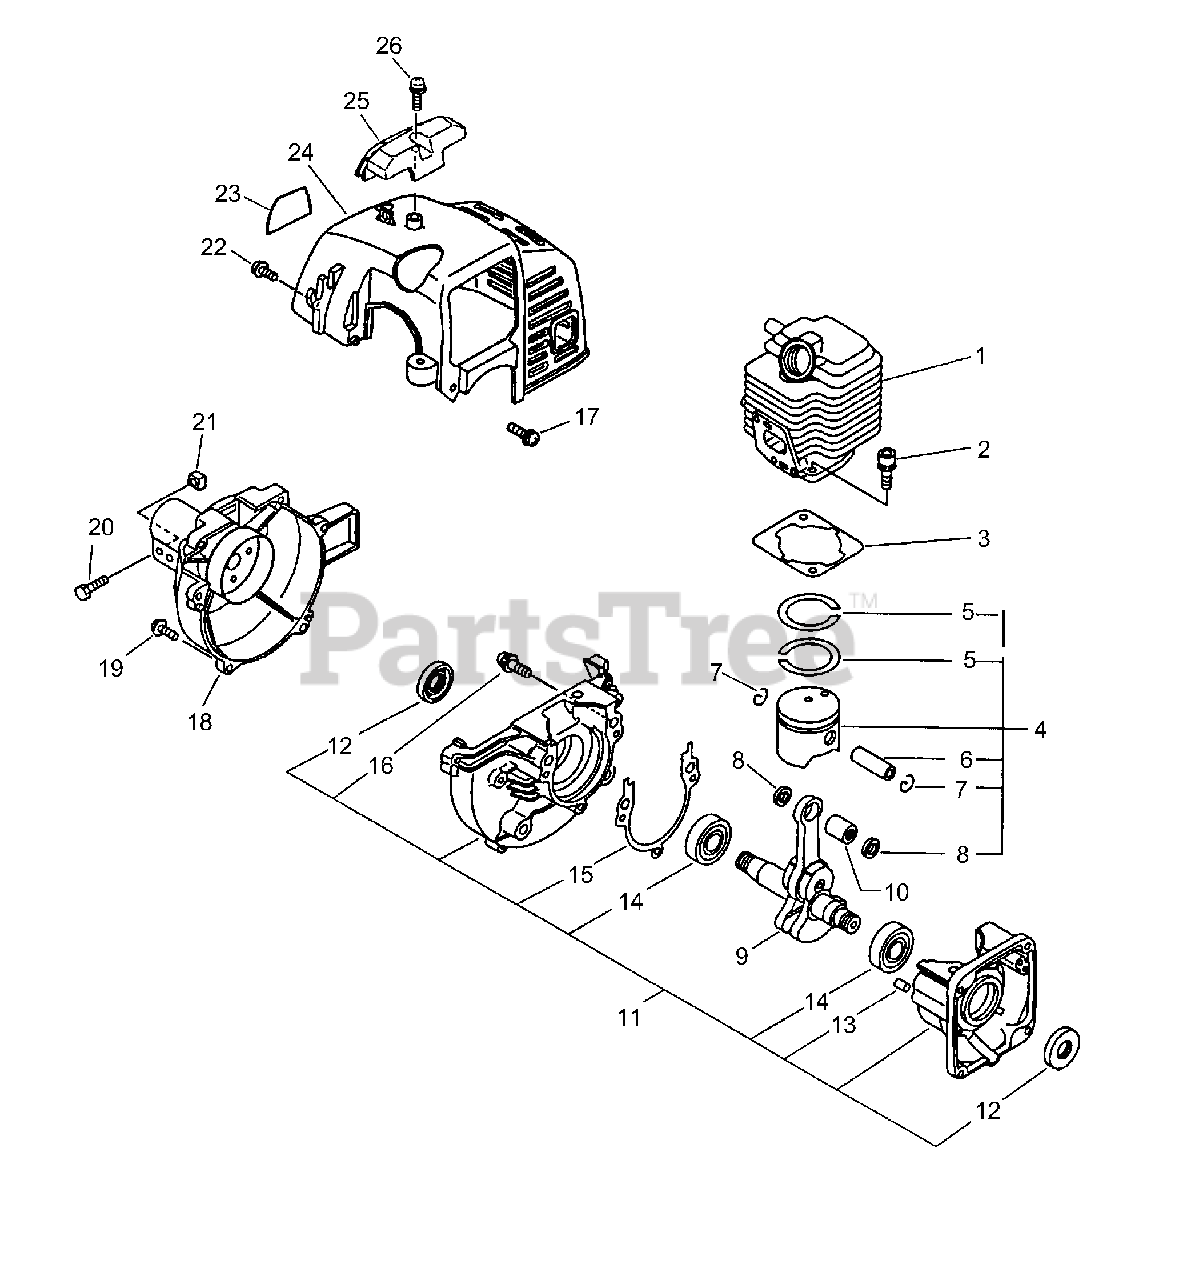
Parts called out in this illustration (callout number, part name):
1	CYLINDER
2	BOLT 5×22
3	GASKET, CYLINDER
4	PISTON KIT
5	RING, PISTON
6	PIN, PISTON 8
7	RING, SNAP
8	WASHER, THRUST
9	CRANKSHAFT ASSY
10	BEARING, NEEDLE
11	CRANKCASE KIT
12	SEAL, OIL 12
13	PIN, LOCATING 4
14	BEARING, BALL - 6201 C3
15	GASKET, CRANKCASE
16	BOLT 5×28
17	SCREW 4×12
18	FAN CASE ASSY
19	BOLT 4×18
20	BOLT 5×28
21	NUT M5
22	BOLT 4×16
23	LABEL, SHC-1700
24	COVER, ENGINE - GRAY
25	GUARD, TOP - GRAY
26	SCREW 5×16
